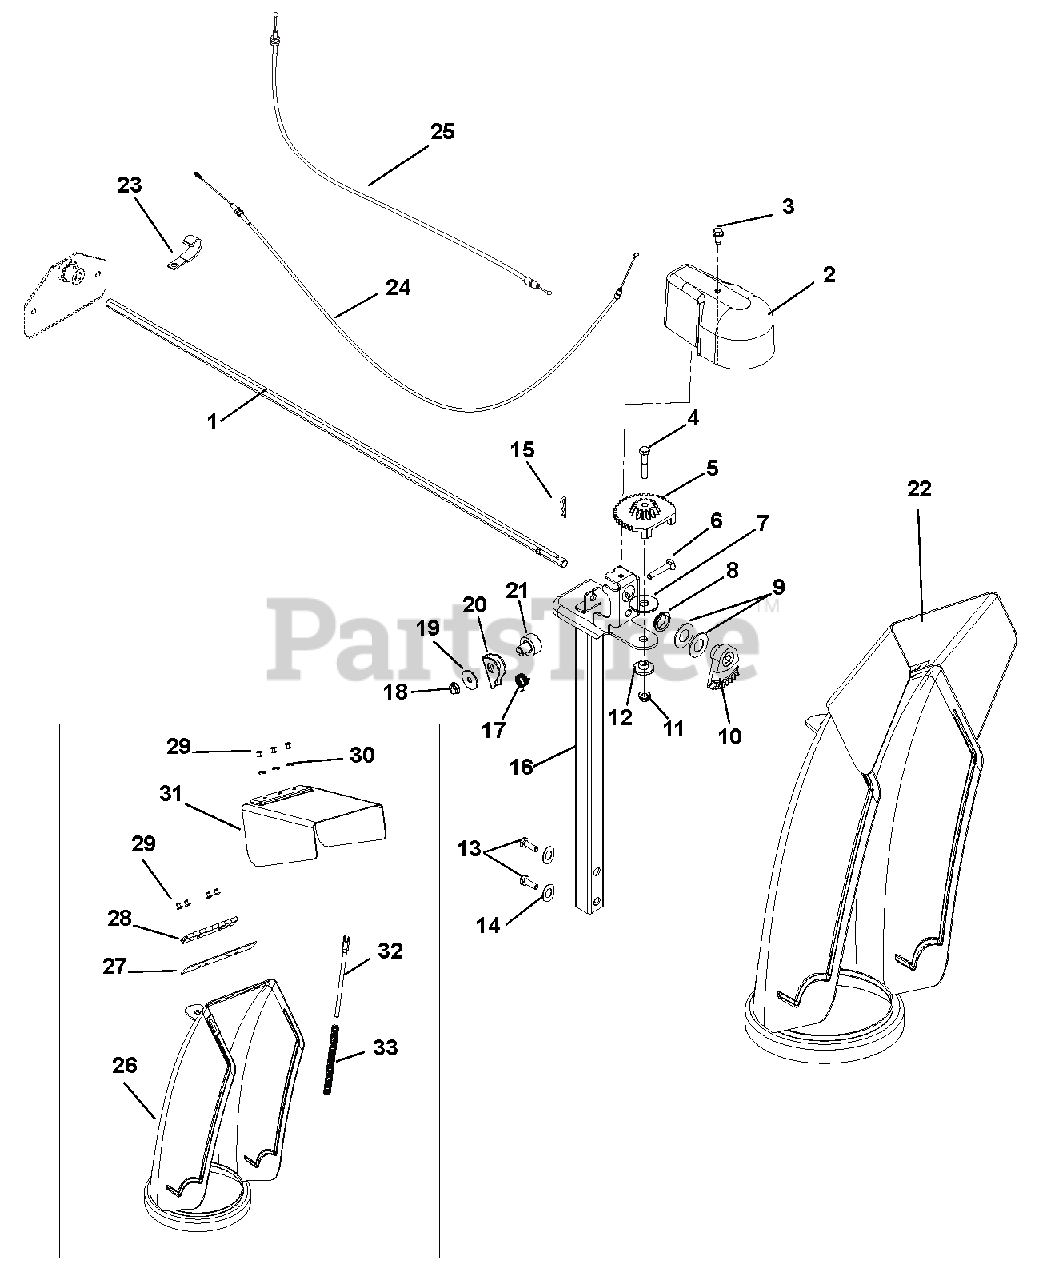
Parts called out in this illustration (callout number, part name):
1	ROD, HEX - CHUTE ROTATION
2	COVER, CHUTE GEAR
3	SCR-TAP .25-20X.50 HWH TR YWZ
4	@BLT-HEX .25-20X1.50 GR5 YWZC
5	GEAR, CHUTE
6	@BLT-RDHDSQNK .25-20X1.50 G5YZ
7	WSHR-FLT-NYL .515X1.375X.093
8	BUSHING, POLYLINER-.75 SNAPIN
9	WSHR-FL-STL.754X1.125X.062YWZC
10	GEAR, CHUTE-ACTUATION
11	@NUT-LK-TOP-FLG .25-20 YWZC
12	BSHG-FLG .265X.477X.375X1.00
13	@BLT-HEX .38-16X1.75 GR5 YWZC
14	@WSHR-LK .38X.094 REG YWZC
15	PIN-HAIR INT .08X.18X1.18 YWZC
16	PEDESTAL, CHUTE - QUICK STICK
17	SG-TORS
18	@NUT-LK-TOP-FLG .25-20 YWZC
19	WSHR-FL-STL .281X1.000X.063
20	ARM, LOCKING
21	BUSHING, LOCK ARM
22	CHUTE, DISCHARGE W/CAP & DECAL
23	J-CLAMP
24	CABLE, DEFLECTOR-COATED
25	CABLE, CHUTE LOCK
26	CHUTE, NOTCHED DISCHARGE
27	CAP SEAL 5.50
29	RVT-POP .187 YZ
30	WSHR-FL-STL .196X.500X.06 YZ
31	CAP, LARGE W/DECAL
32	ROD, DEFLECTOR CAP
33	SG-TENS .06X.492X5.25
